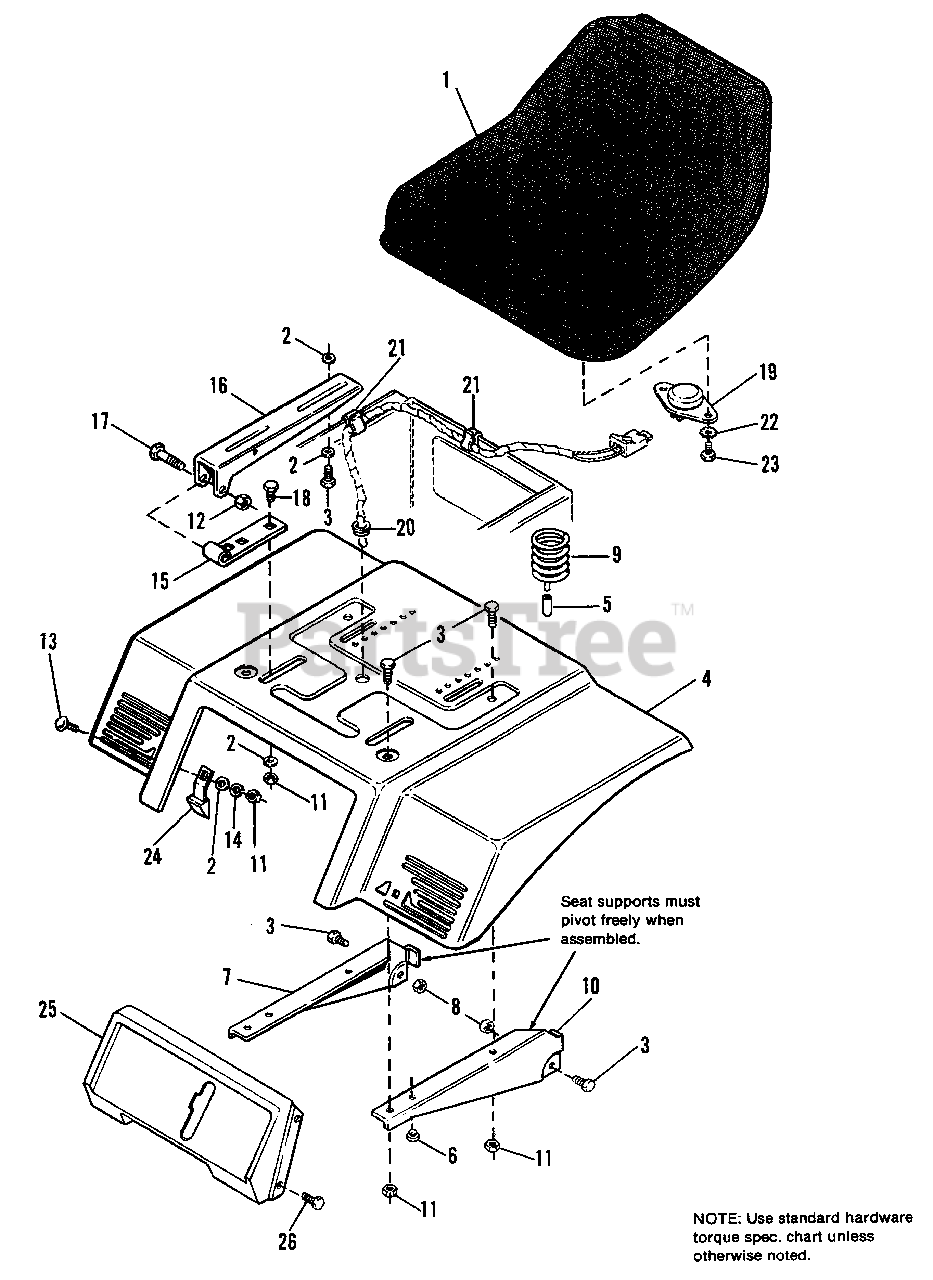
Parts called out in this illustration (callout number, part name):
2	WASHER, Plain, 5/16
3	CAPSCREW, Hex, 5/16-18 x 3/4
4	DECK, Seat
5	COVER, Wire
6	BUMPER, Plug
7	SUPPORT, Seat, R.H.
8	LOCKNUT, Hex, 5/16-18
9	SPRING, Seat
10	SUPPORT, Seat, L.H.
11	NUT, Hex, full, 5/17-18
12	LOCKNUT, Hex, 3/8-16
13	BOLT, Carriage, 5/16-18 x 3/4
14	LOCKWASHER, 5/16
15	HINGE, Lower
16	HINGE, Upper
17	CAPSCREW, Hex, 3/8-16 x 2
18	CAPSCREW, Hex, 5/16-18 x 1.0
19	SWITCH, Seat
20	BUSHING, Snap
22	LOCKWASHER, 1/4 Ext. Tooth
23	SCREW, Rd. Hd., 1/4-20 x 1/2
24	SEAT LATCH ASSY.
25	PANEL, Shift
26	SCREW, Tapttie, 5/16-18 x 3/8
